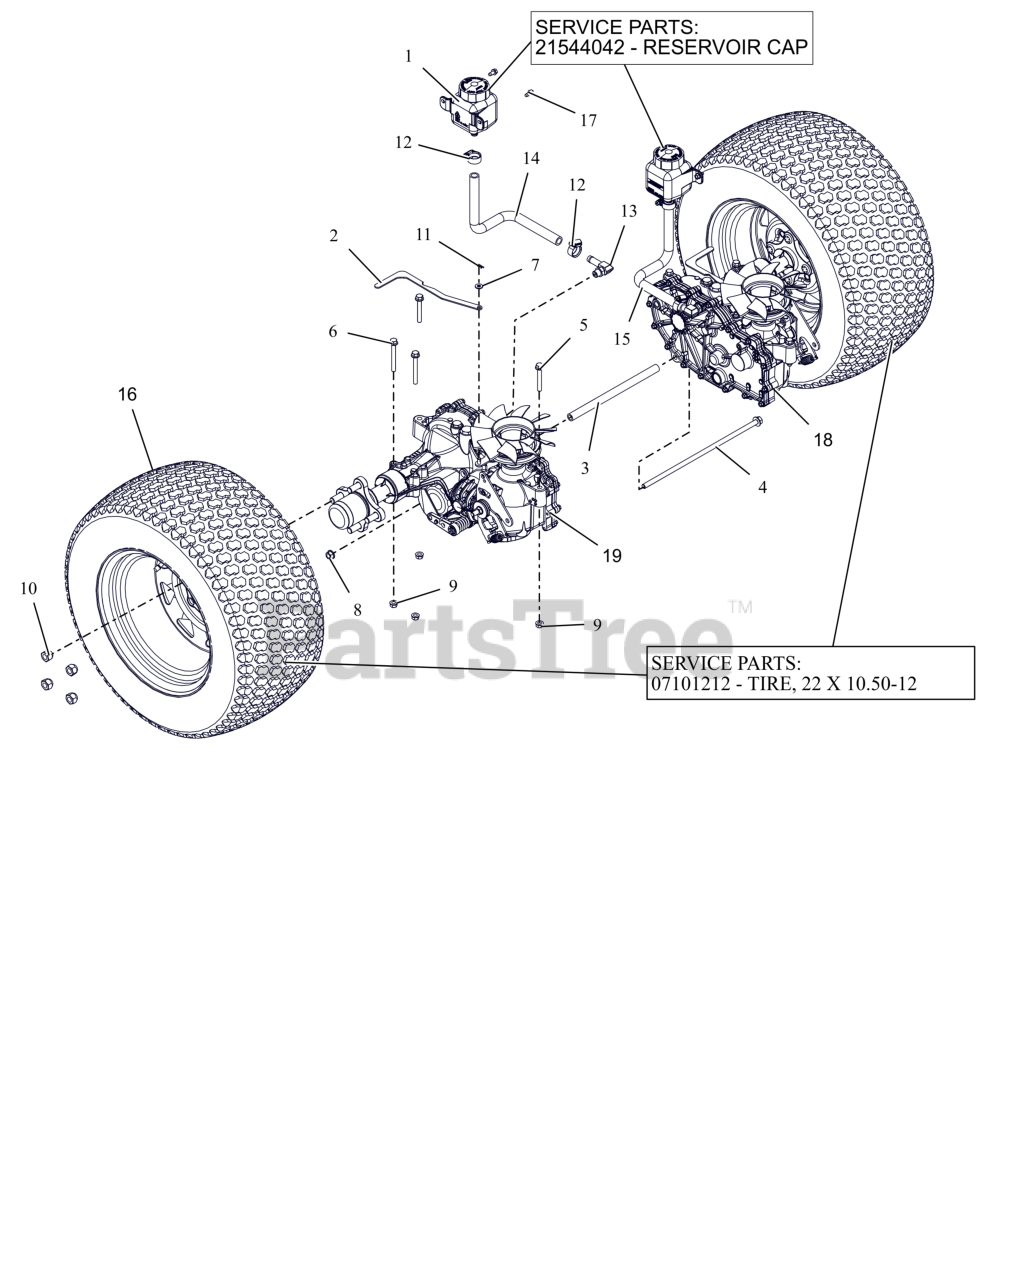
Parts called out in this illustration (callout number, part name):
1	TANK, EXPANSION
1	CAP, HYDRO RESERVOIR REPLAC.
2	BRKT, VALVE DUM
3	SPCR, TRANSAXLE .406 ID X .630 OD X 9.95LG (BLACK)
4	BLT, HEX-FLG 0.375-16X13 GR5 ZC120
5	BLT,HEX-FLG .31-18X2.25 G5 ZCC
6	BLT,HEX-FLG .31-18X2.75 G5 ZCC
7	WSHR,FLT .281X.625X.065 ZCC
8	NUT-LK-TOP-FLG .38-16 ZC120
9	NUT,LK-CTR-FLG .31-18 GF ZCC
10	NUT, WHEEL .50-20 ZCC
11	PIN, HAIR #225 .072X1.09
12	CLAMP,.88 DIA. HOSE
13	FITTING, HYD (90 DEG)
14	HOSE, FORMED EXPANSION -HD RH
15	HOSE, FORMED EXPANSION -HD LH
16	ASM, WHL/TIRE 22X10.50-12 K500
16	TIRE, 22X10.50-12
17	SCR-TAP .25-20X.50 HWH ZCC
18	TRANSAXLE, ZT3200 - LH
19	TRANSAXLE, ZT3200 - RH
